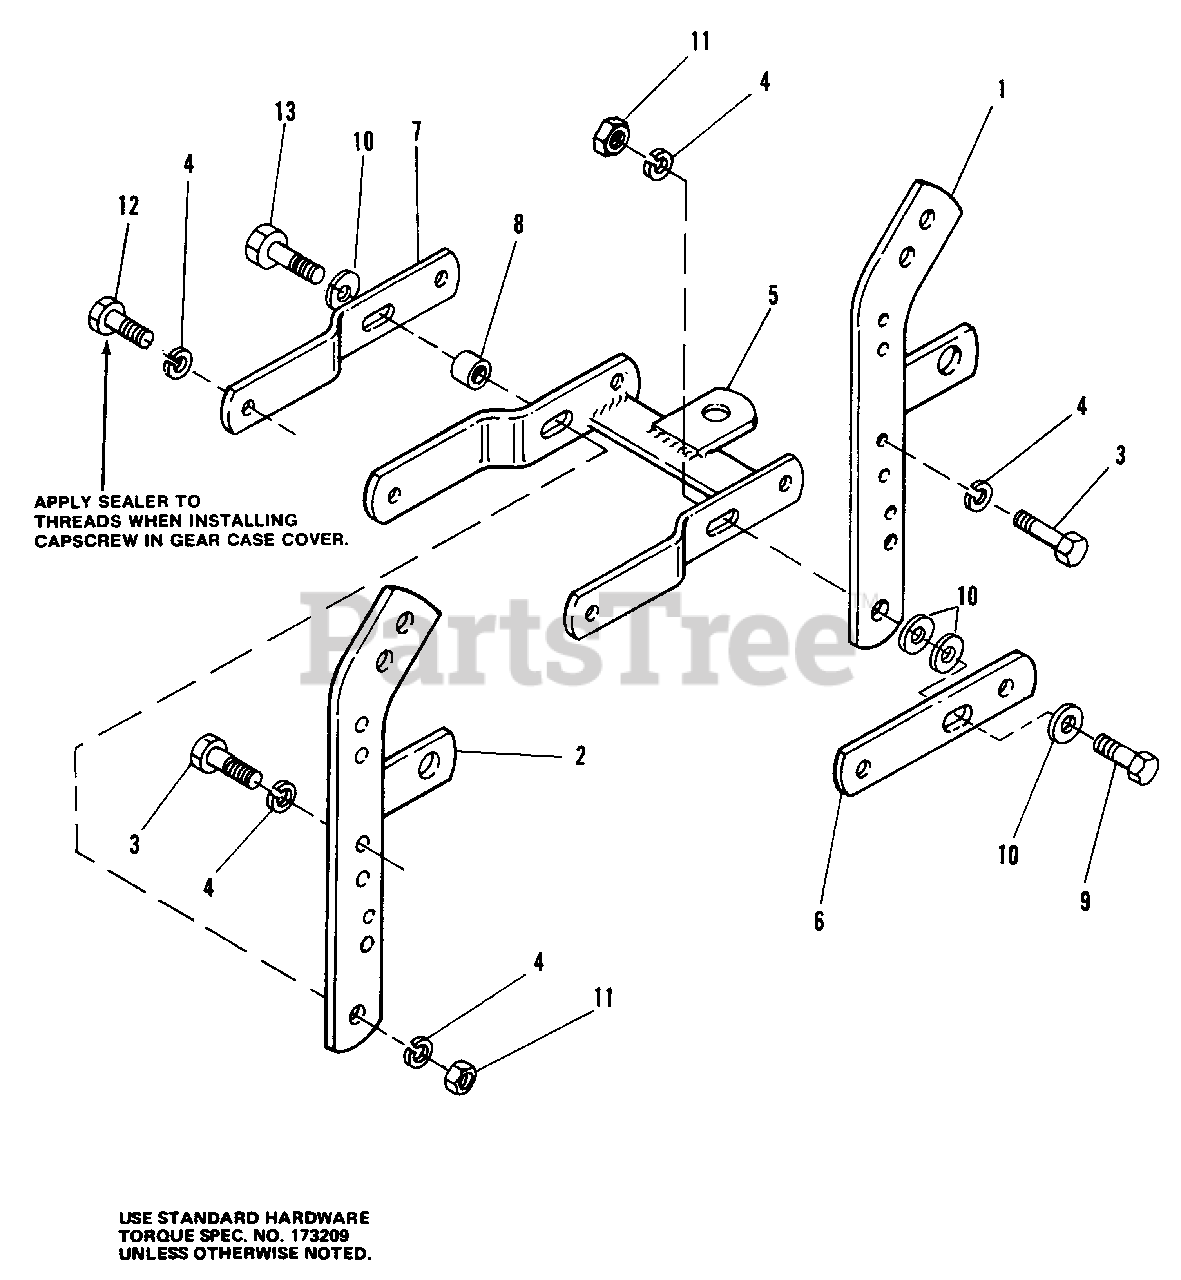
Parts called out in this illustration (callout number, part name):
1	L.H. ARM ASSEMBLY
2	R.H. ARM ASSEMBLY
3	CAPSCREW, Hex Hd., 7/16-14 x 1
4	LOCKWASHER, 7/16
5	DRAWBAR ASSEMBLY
6	BAR, Pull, L.H.
7	BAR, Draw, R.H.
9	CAPSCREW, Hex Hd., 7/16-14 x 1-1/2
10	WASHER, 7/16
11	NUT, Hex, 7/16-14
12	CAPSCREW, Hex Hd., 7/16-14 x 1-3/4
13	CAPSCREW, Hex Hd., 7/16-14 x 2-1/4
